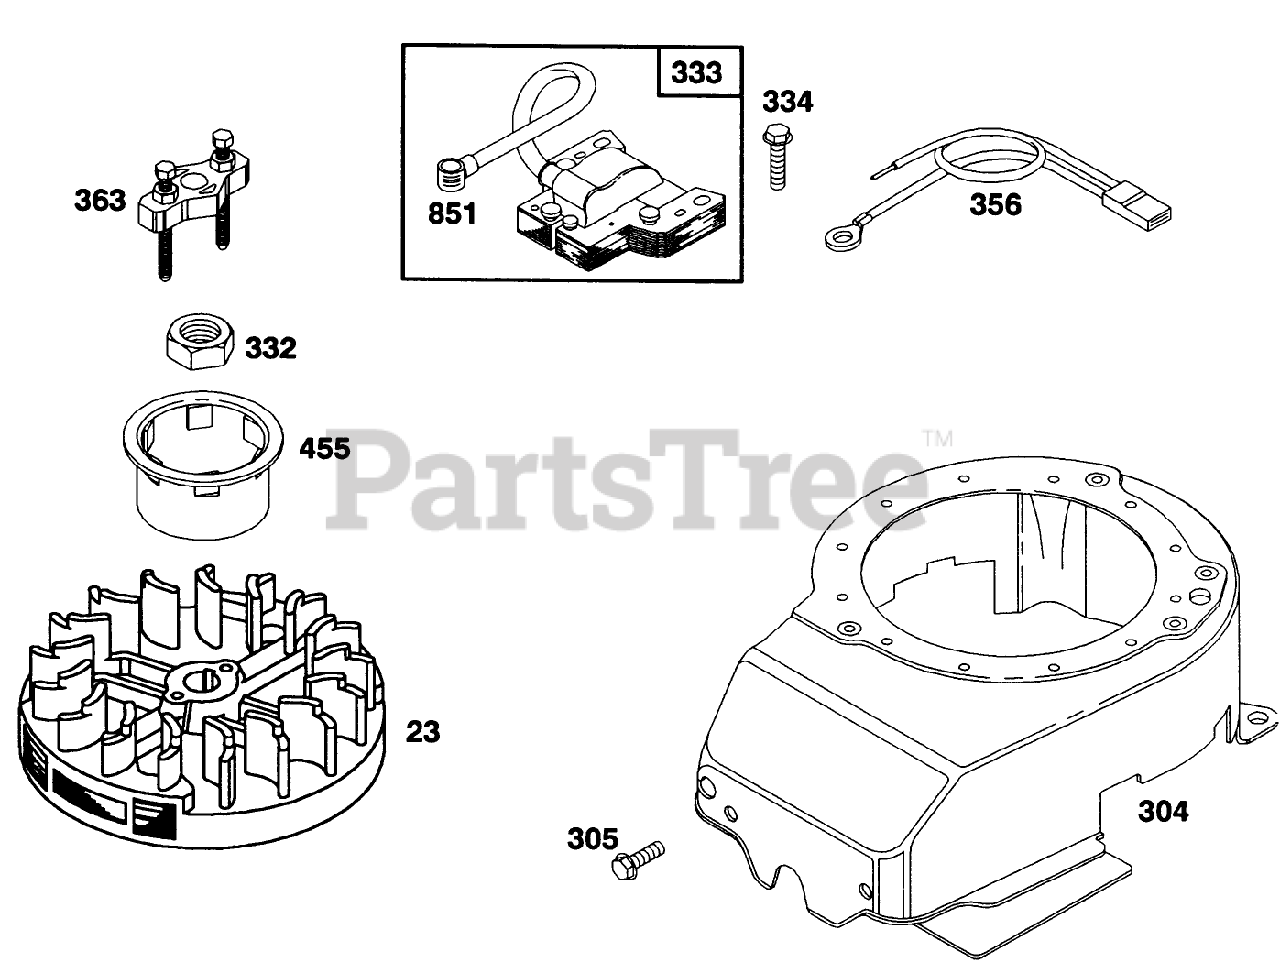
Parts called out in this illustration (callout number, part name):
23	Flywheel
304	Housing-Blower
305	Screw-Sem
333	Armature-Magneto
334	Screw
356	Wire Stop
363	Puller-Flywheel
455	Cup-Starter
851	Terminal-Cable
